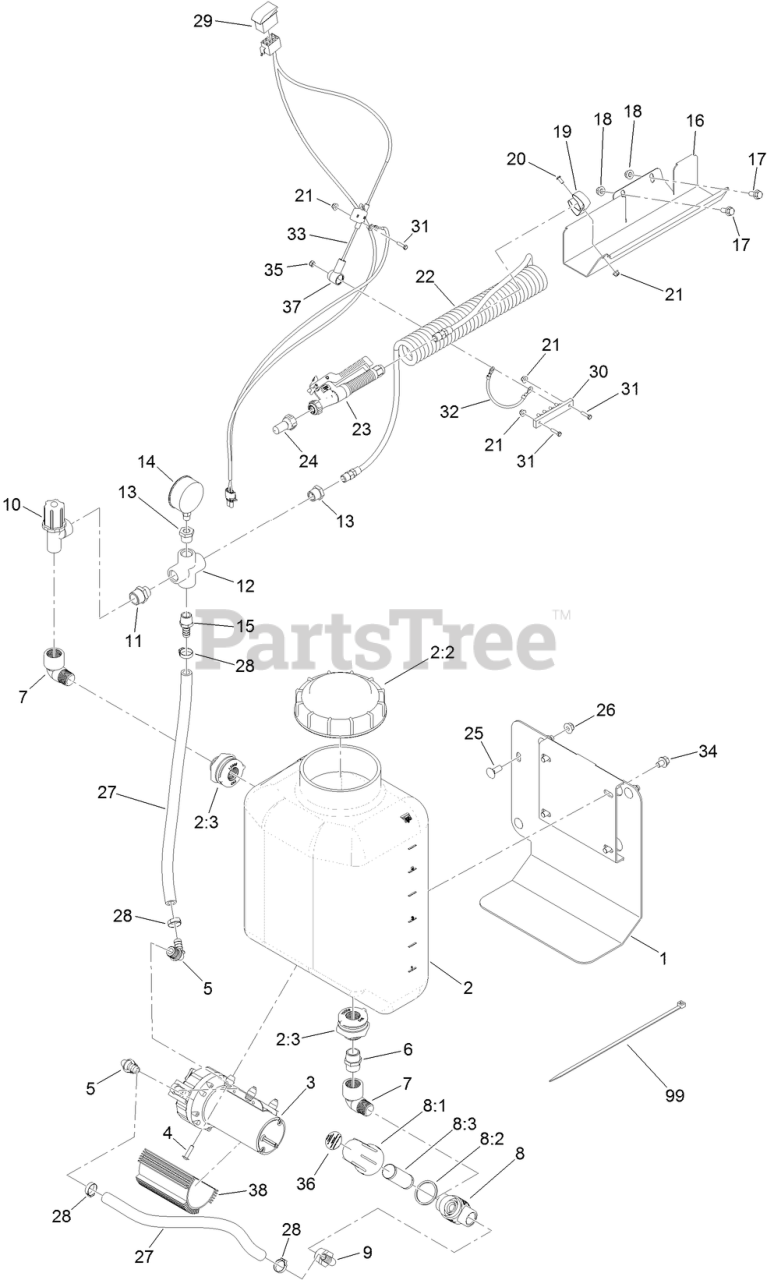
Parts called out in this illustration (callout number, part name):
1	MOUNT-AUX/ISO, 7GAL RT
2	ASM-TANK, AUX/ISO, 7GAL RT
2:2	CAP-TANK, SPRAY
2:3	FITTING-BULKHEAD
3	PUMP-5.3 GPM
4	SCREW-HSBHF
5	FITTING-ELBOW, BARBED
6	FITTING-NIPPLE
7	ELBOW-90 DEG
8	STRAINER-INLINE
8:1	BOWL-STRAINER
8:2	GASKET-HEAD, LINE STRAINER
8:3	SCREEN-STRAINER, 50 MESH
9	FITTING-ELBOW, 90
10	VALVE-THROTTLE
11	FITTING-NIPPLE
13	FITTING-REDUCER
14	GAUGE-PLAIN
15	FITTING-HOSEBARB
16	TRAY-GUN, 7GAL RT
17	SCREW-HHF
18	NUT-HEX FLANGE
19	HOLDER-TOOL, CLIP
20	SCREW-HSBH
21	NUT-HEX FLANGE
22	HOSE-COILED, 15 FT
23	GUN-SPRAY, SPOT
24	TIP-SPRAY, #12 SPOT
25	SCREW-CARR
26	NUT-HEX FLANGE
27	HOSE-SPRAY
28	CLAMP-OETIKER, 167
29	SWITCH-ROCKER
30	BLOCK-TERMINAL
31	SCREW-HH
32	HARNESS-WIRE, JUMPER
33	HARNESS-ACCESSORY
34	SCREW-HHF
35	NUT-HEX
36	DECAL-CAP, STRAINER
37	INSULATOR-SOLENOID
38	HEATSINK-3.0"
99	TIE-CABLE
